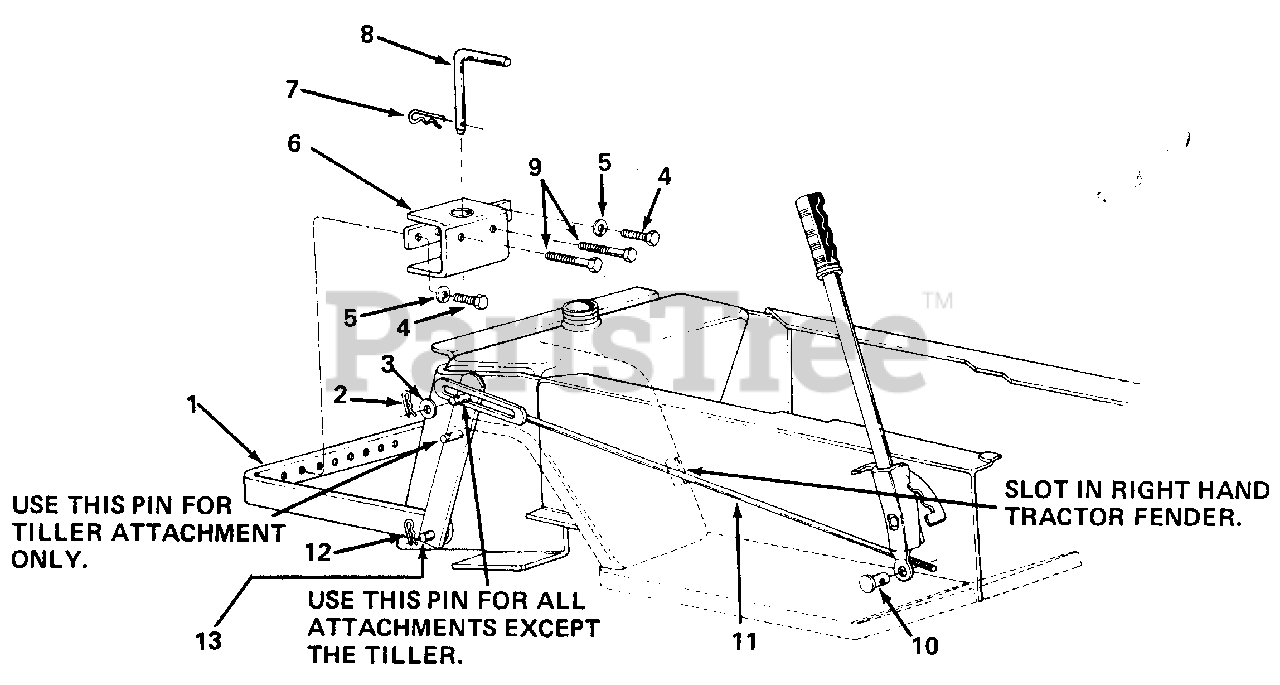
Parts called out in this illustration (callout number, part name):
3	Fl.Wash. 1/2" I.D.
4	Hex Scr. 1/2-13 x 1.00" Lg.*
5	L.Wash. 1/2" Scr.*
8	Hitch Pin
9	Hex Scr. 1/2-13 x 3.00" Lg.*
10	Adjustment Ferrule
13	Hitch Rod
